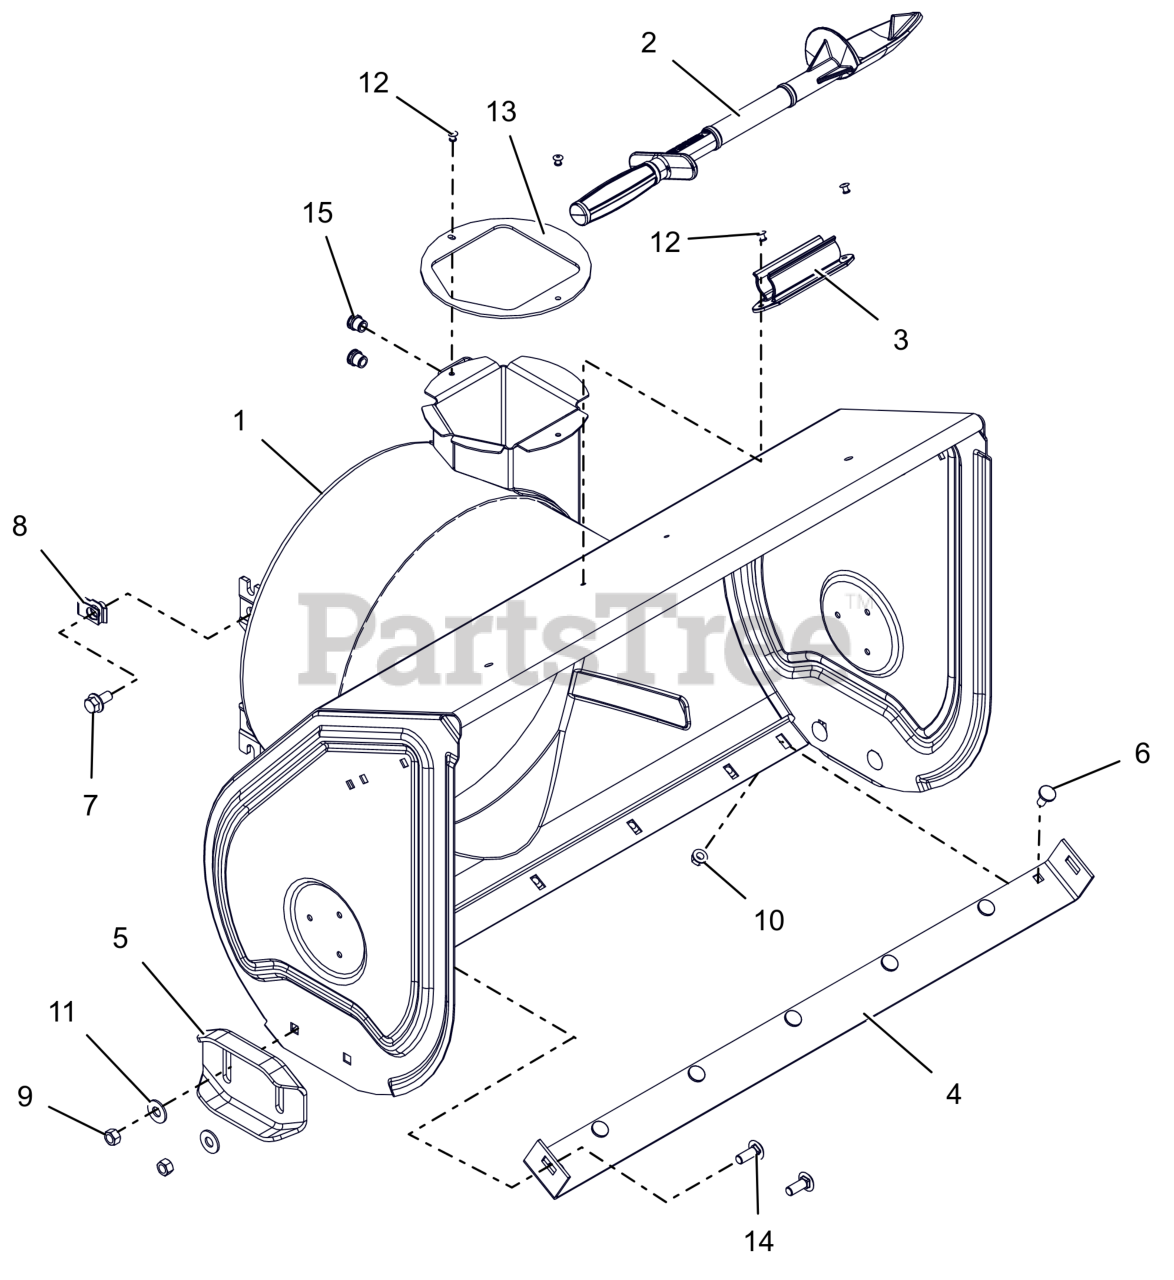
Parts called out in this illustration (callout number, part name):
1	BLOWER HOUSING W/DECAL 30"
2	DEVICE, SNOW CLEAN OUT
3	MOUNT, SNOW CLEAN OUT
4	BLADE, SCRAPER-30"
5	SKID SHOE, REVERSIBLE - ORANGE
6	BOLT, MODIFIED HEAD CARRIAGE
8	NUT-RTNR .375-16X.37
9	NUT-LK-CTR .38-16 ZC120
10	NUT-LK-TOP-FLG .312-18 GF ZCC
11	WSHR,FLT .438X1.00X.083 ZCC
12	RVT, POP .1875 ZCC
13	BAFFLE, DISCHARGE NECK
14	BLT,RHSSN .38-16X1.00 G5 ZCC
15	NUT,THD,INSERT .38-16 ZC120
